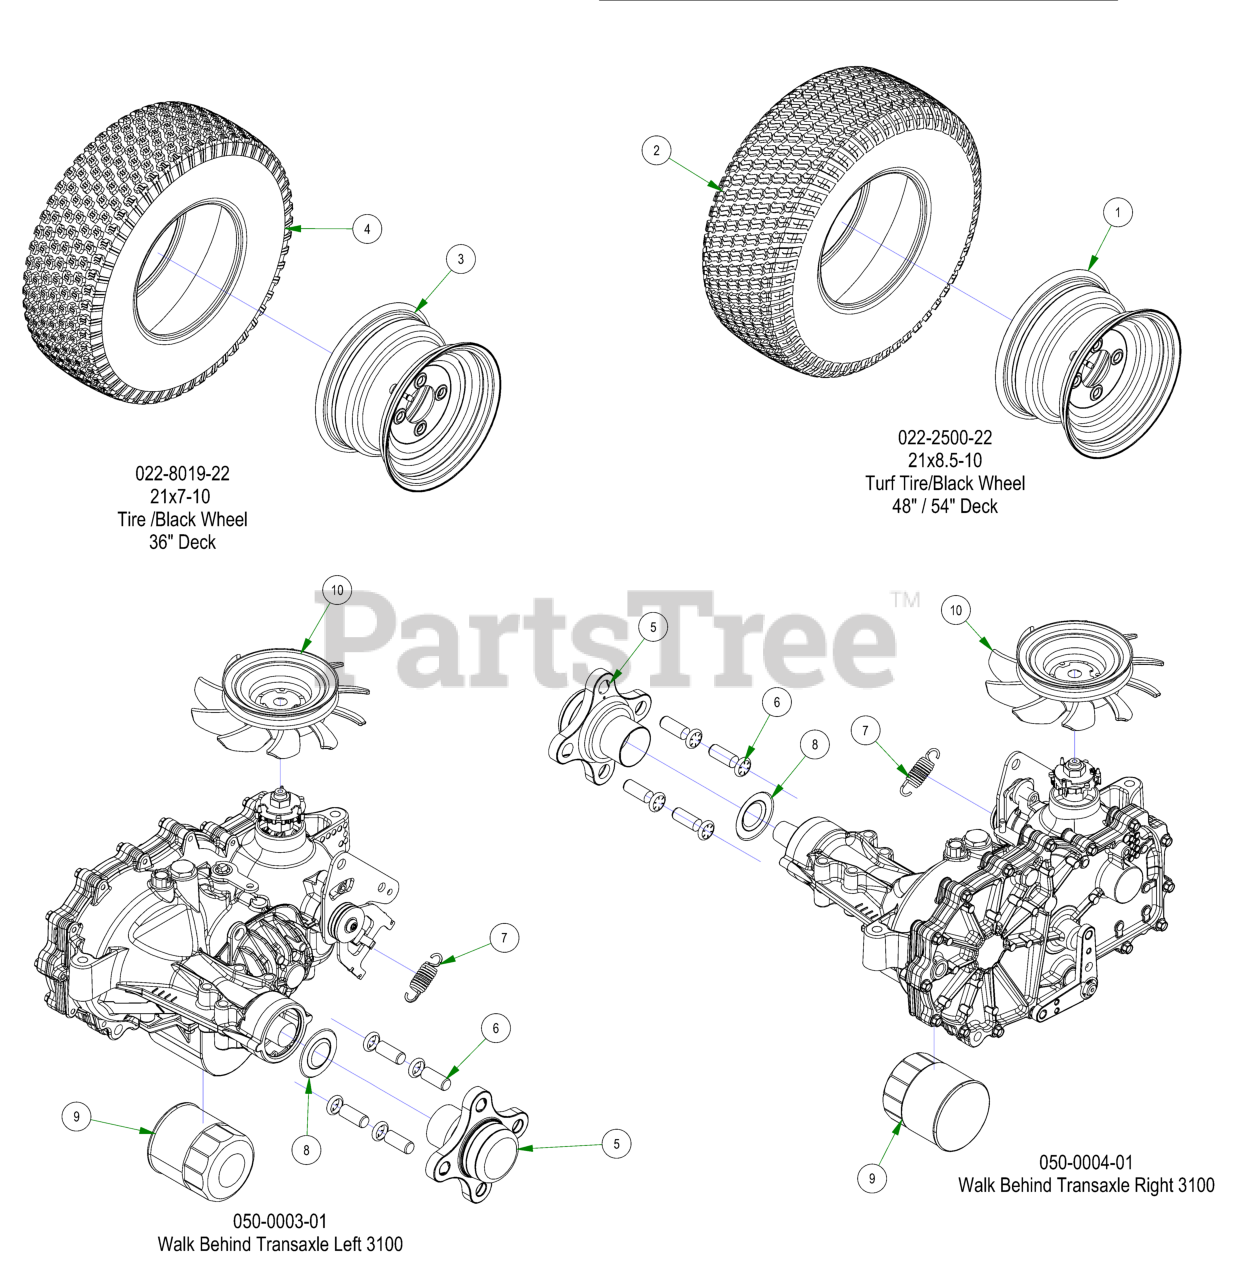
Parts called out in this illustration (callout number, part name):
1	Rim for 022-2500-22
2	Tire for 022-2500-22
3	Black 10" Wheel Only-36" Stand On
4	Walk Behind 36" Tire Only 21 X 7 - 10
5	ZT Transaxle Wheel Hub
6	Transaxle Wheel Studs/ Drum Brake Studs
7	Gold Transaxle Spring
8	2021 ZT/Maverick Transaxle Seal Kit (ZT-2800)
9	ZT Hydraulic Filter
10	2021 ZT/Maverick Transaxle Fan/Pulley Kit
